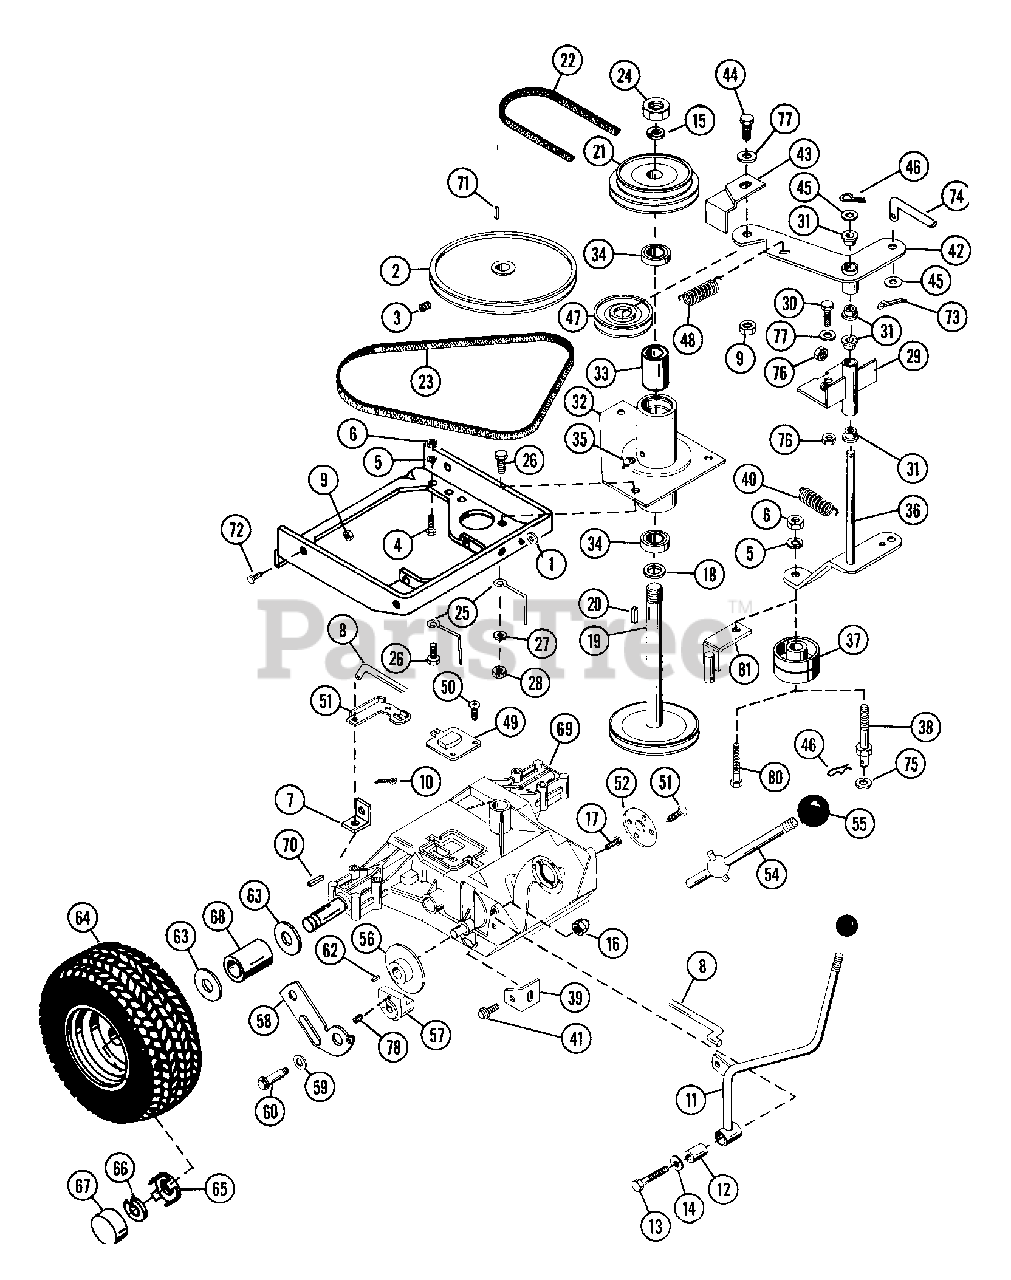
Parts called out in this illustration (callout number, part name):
1	TRANSAXLE MOUNT
2	PLY-V 6.00 X .63 W/KEY (ADAMS)
3	SCR-SET .25-20X.25 SKHCUPNY OH
4	BLT-HEX .38-16X2.75 PL GR5
5	WSHR-LK .375X.115 HVY PL
6	NUT-HEX .375-16
8	SELECTOR ROD
9	NUT-LK TOP .375-16 GR C YWZC
10	PIN-COTR .09X.75 PL
11	RANGE SELECTOR LEVER
12	SPACER .50 X .32 X 1.00
13	BLT-HEX .25-20X2.00 PL GR5
14	WSHR-FL-STL.312X.734X.065PL
15	WSHR-LK-INT .750X.050 MED
16	NUT-LK TOP .250-20 PL
17	BLT-HEX .25-20X1.00 PL GR5
18	WSHR-FL-STL .755X1.250X.125
19	JACKSHAFT SPINDLE
20	KEY-SQ .188X1.0X.188 SAE 8630
21	DOUBLE SHEAVE
22	V-BELT, 4L-RAW EDGE
23	V-BELT, 4L-RAW EDGE
24	NUT-JAM .75-10 PL
25	BELT FINGER
26	BLT-HEX .31-18X1.00 PL GR5
27	WSHR-LK .375X.115 HVY PL
28	NUT-LK-NYL .375-24 PL
29	IDLER PIVOT
30	BLT-HEX .31-18X.75 PL GR5
31	BSHG-FLG .372X.500X.312X.625NY
32	SPINDLE HOUSING
33	BEARING SPACER .770X1.00X3.268
34	BRG-BALL .750X1.781X.61
35	SPIN DRIVE ZERK FITTING
36	IDLER ARM
37	IDLER-FLAT 2.25 X .38
38	IDLER MTG BOLT
39	SPRING ANCHOR
40	SG-TENS .091X.73X5.28 WLD 30
41	BLT-SERHFWH .31-18X.50 PL
42	IDLER ARM
43	BELT RETAINER
44	BLT-HEX .38-16X1.75 PL GR2
45	WSHR-FL-STL .382X.812X.023 PL
46	PIN-HAIR INT .08X.18X1.18
47	IDLER-V 3.06 X .38
48	SG-TENS .105X.812X3.88 WLD 15
49	HI-LO COVER PLATE
50	SCR-MCH 8-32X.50 SLTR PL
51	SCR-MCH 10-24X.50 SLTR PL
52	NYLON COVER
53	HI-LO SHIFT LEVER
54	SHIFT LEVER ASSY
55	SHIFT BALL
56	BRAKE DISC
57	BRAKE JAW ASSY
58	ACTUATING LEVER ASSY
59	SHIM KIT
60	SHOULDER BOLT
61	FRICTION PAD
62	KEY-WDRF .188X.625X.25 SAE 61
63	WSHR-FL-STL .755X1.375X.062 PL
64	WHEEL & TIRE ASSEMBLY
65	SPINDLE CUP
66	RG-RTNG-EXT .750X.050
67	HUB CAP
68	SPACER 1.000 X .760 X 1.562
69	TRANSAXLE ASSEMBLY
70	KEY-SQ .188X2.0X.188 SAE 8630
71	KEY-WDRF .188X.75X.313 SAE 9
72	BLT-HEX .38-16X1.00 PL GR5
73	PIN-COTR .12X1.0 PL
74	CLUTCH ROD
75	WSHR-FL-STL .382X.812X.062
76	NUT-LK-TOP .312-18 GR C PL
77	WSHR-FL-STL .38X.875X.083 PL
78	SCR-SET 8-32 FOOTE 1606
80	BLT-HEX .38-16X1.75 PL GR2
81	BRACKET
